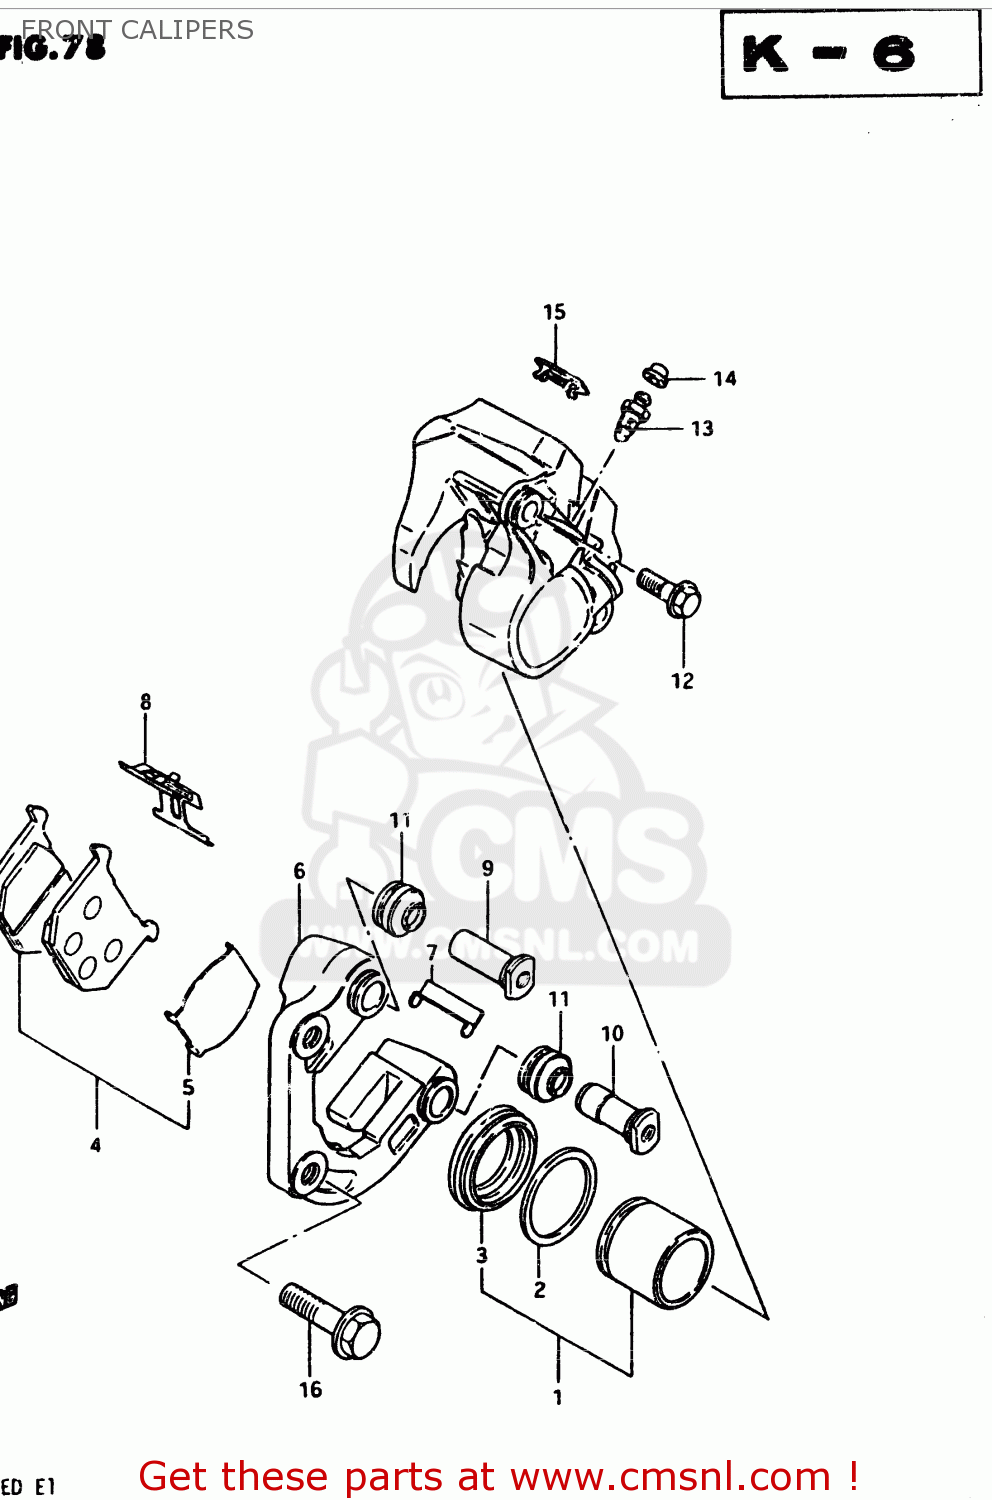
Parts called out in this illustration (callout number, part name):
1	PISTON SET
2	SEAL,FR CALIPE
3	BOOT,PISTON
4	PAD SET (MCA)
5	SHIM,PAD
6	CARRIER,CALIPER,LEFT
7	GUIDE,PAD
8	SPRING,PAD
9	AXLE NO.1
10	AXLE NO.2
11	BOOT,AXLE
12	BOLT
13	BLEEDER
14	CAP,BREATHER
15	COVER
16	BOLT 10X37
